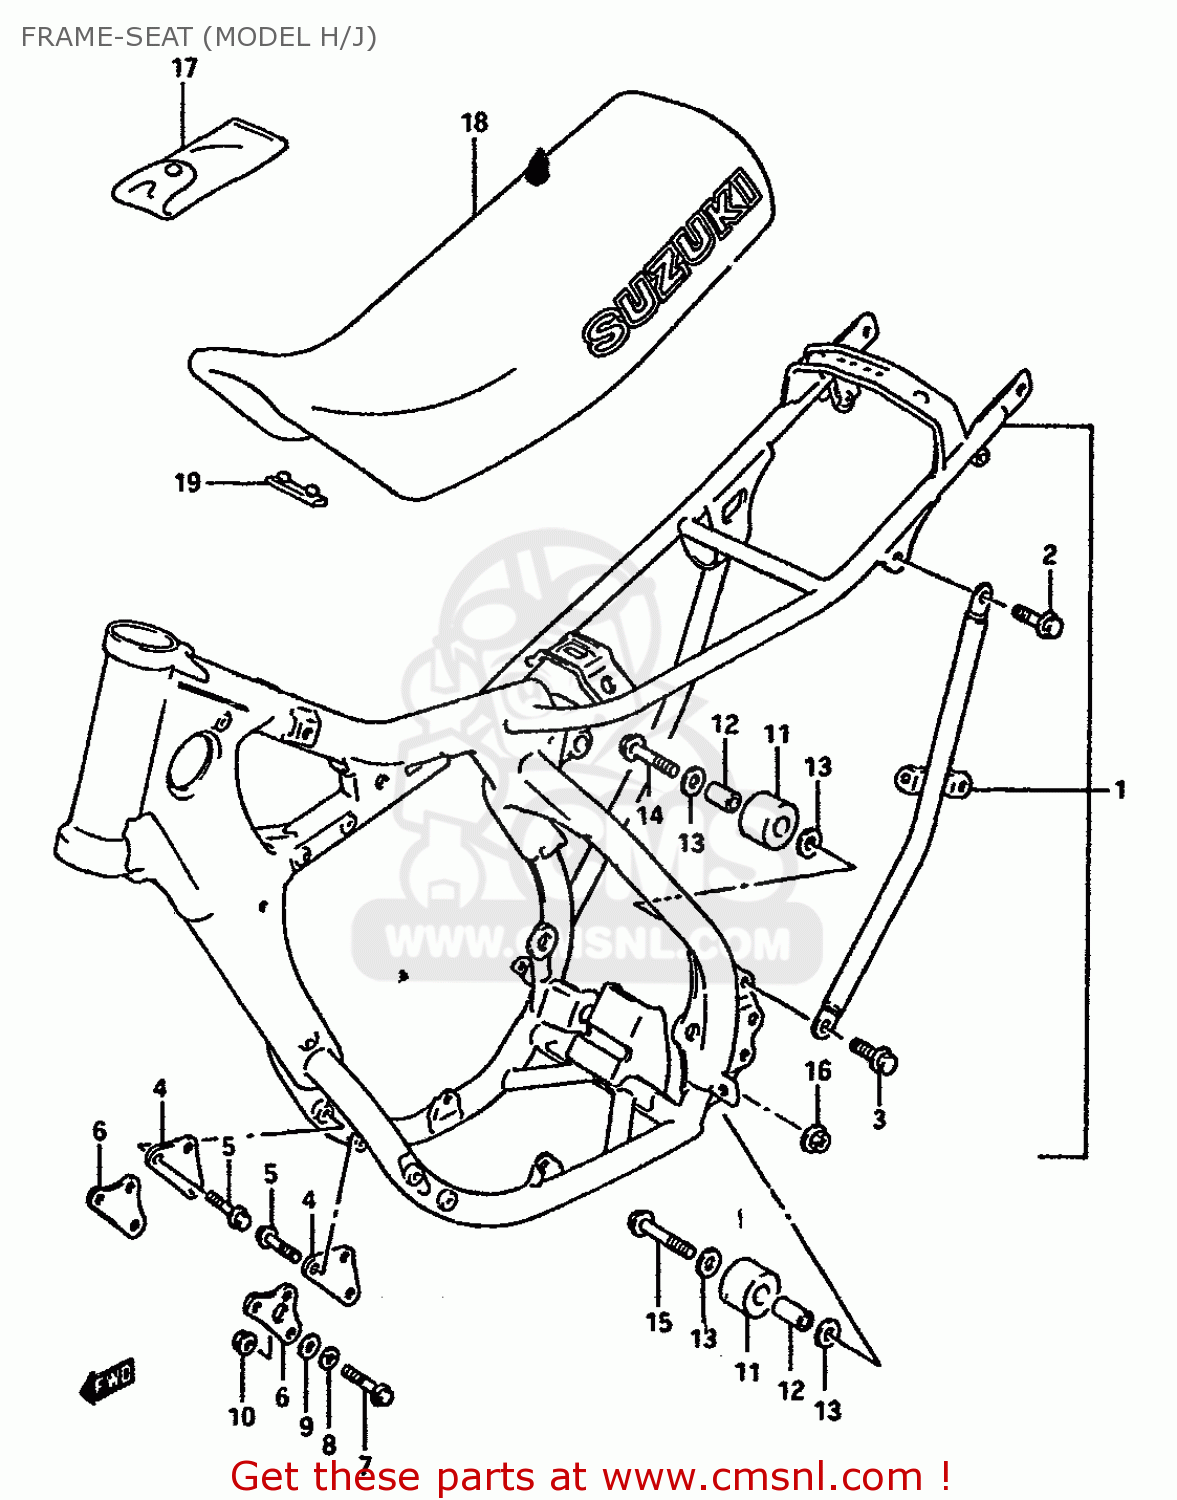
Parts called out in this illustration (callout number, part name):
1	FRAME
2	BOLT
3	BOLT
4	PLATE,ENGINE MOUNTING
5	BOLT(8X36)
6	PLATE,ENGINE MOUNTING,FRONT
7	BOLT 8X55
8	LOCK WASHER
9	WASHER
10	NUT
11	ROLLER,CHAIN CONTROL
12	SPACER (8.6X13.8X28)
13	WASHER
14	BOLT(8X45)
15	BOLT 8X55
16	NUT
17	TOOL SET
18	SEAT ASSEMBLY
19	CUSHION
